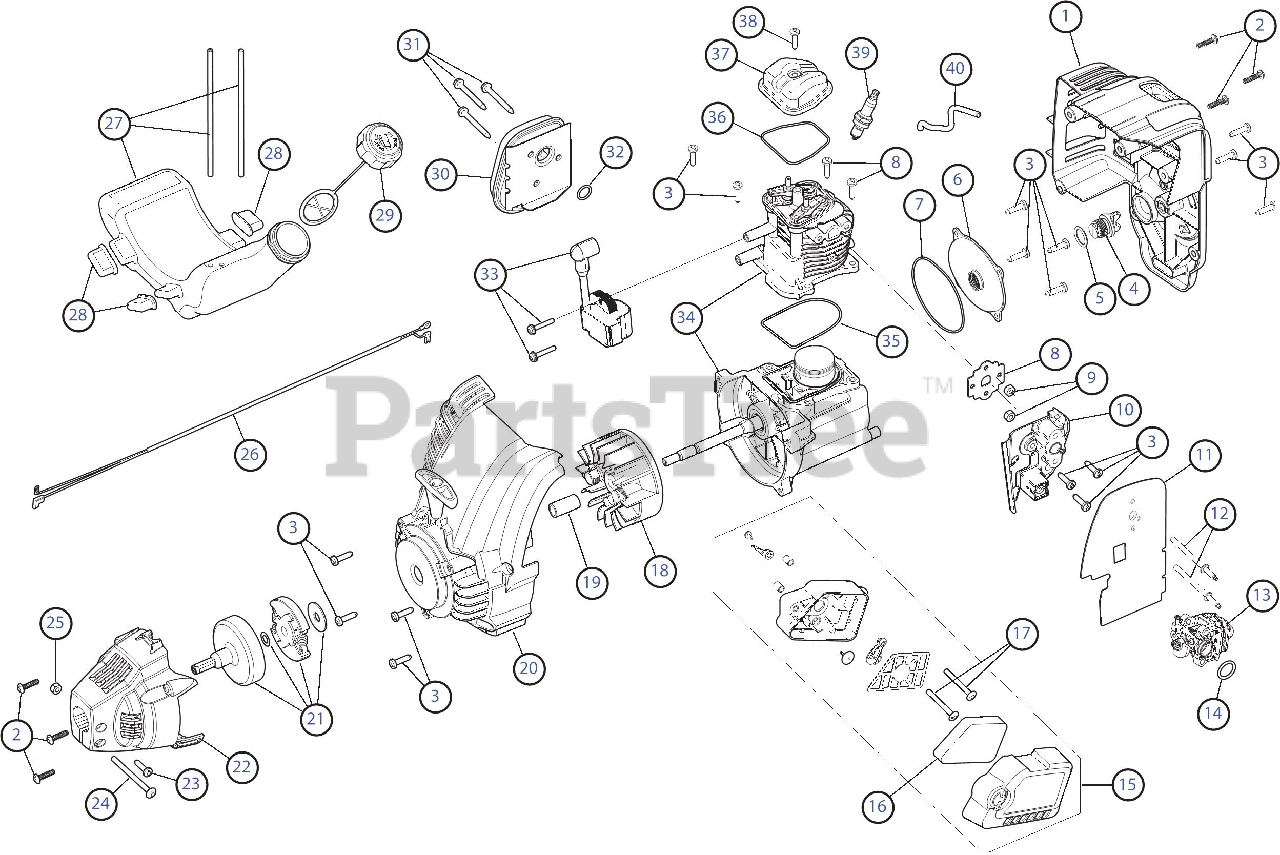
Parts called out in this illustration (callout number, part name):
1	Engine Cover Assembly
2	Cover Screw
3	Starter Screw
4	Oil Plug
5	Oil Plug O-Ring
6	Crank Case Cover
7	Crank Case Cover O-Ring
8	Insulator Gasket
9	Insulator Nut
11	Carburetor Gasket
12	Air Filter Mounting Screw
13	Carburetor
14	Carburetor O-Ring
15	Air Cleaner Cover Assembly
16	Air Filter
17	Air Filter Screw
18	Flywheel Assembly
20	Starter Housing Assembly
21	Clutch Assembly
22	Clutch Cover
23	Anti-Rotation Screw
24	Clamp Screw
25	Clamp Nut
26	WIRE LEAD
27	Fuel Tank Assembly
28	Fuel Tank Cap
29	Fuel Tank Pads
30	Muffler Assembly
31	Muffler Screw
32	Muffler Gasket
33	Module Assembly
34	Shortblock Assembly
35	Cylinder O-Ring
36	Rocker Cover O-Ring
37	Rocker Cover
38	Rocker Cover Screw
39	Spark Plug
40	Breather Hose
